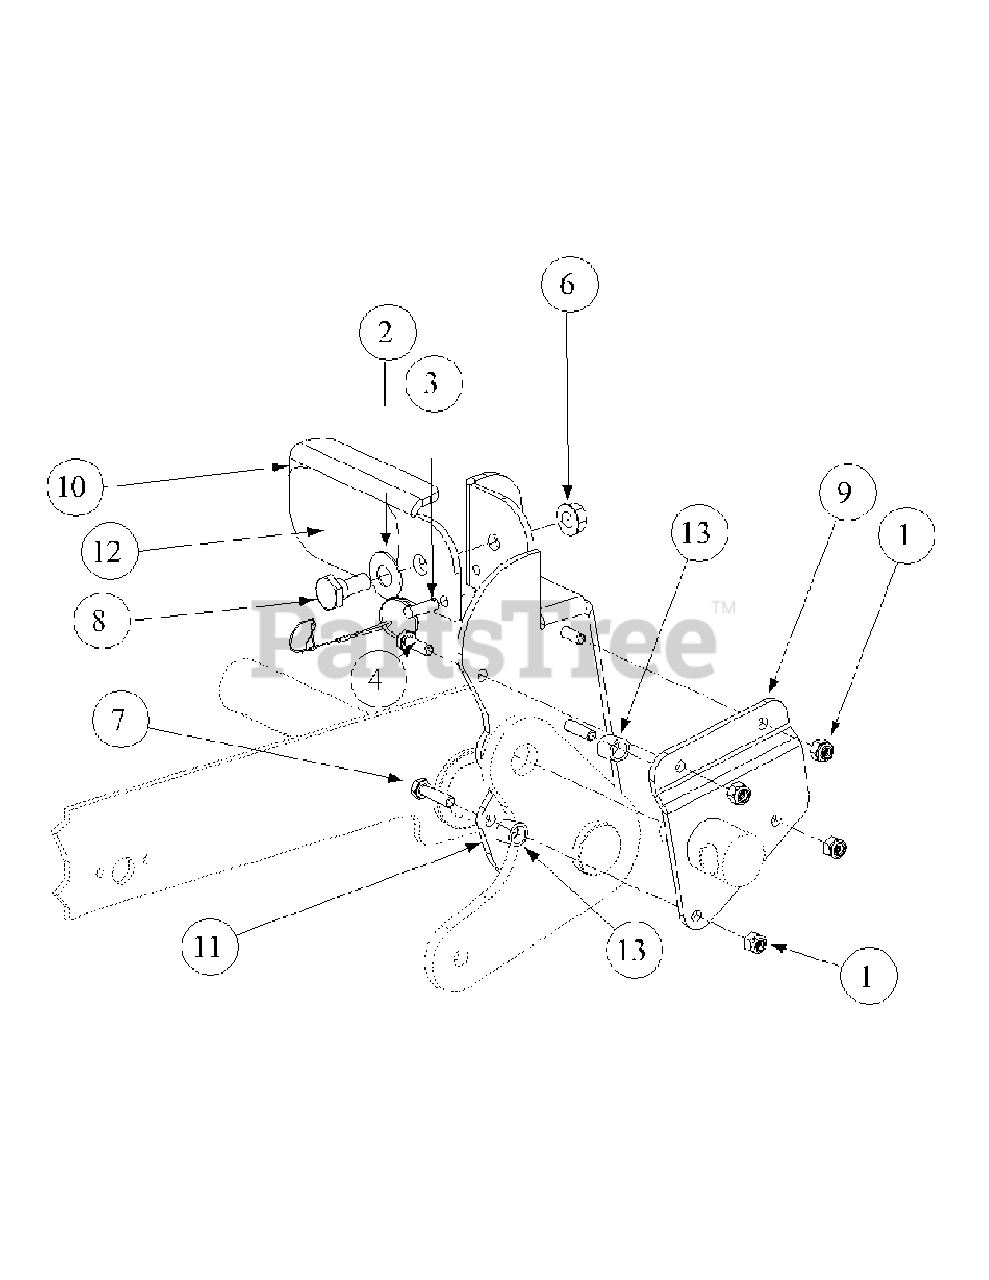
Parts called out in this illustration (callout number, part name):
1	Lock Nut, Nylon Insert, 1/4-20
2	Washer, 1/2 x 1 Shim
3	Detent Pin w/12" Lanyard
4	Hex Cap Screw, 1/4-20, .75
6	Hex Nut, Flange Lock 3/8-16
7	Hex Cap Screw, 1/4-20, 1.00
8	Shoulder Screw, .50 x .27 Lg., 3/8-16 1
9	Foot Lift Backup Pedal
10	Deck Foot Pedal Lift
11	Deck Foot Pedal Lift
12	Deck Foot Lift Pad
13	Turnbuckle Sleeve
